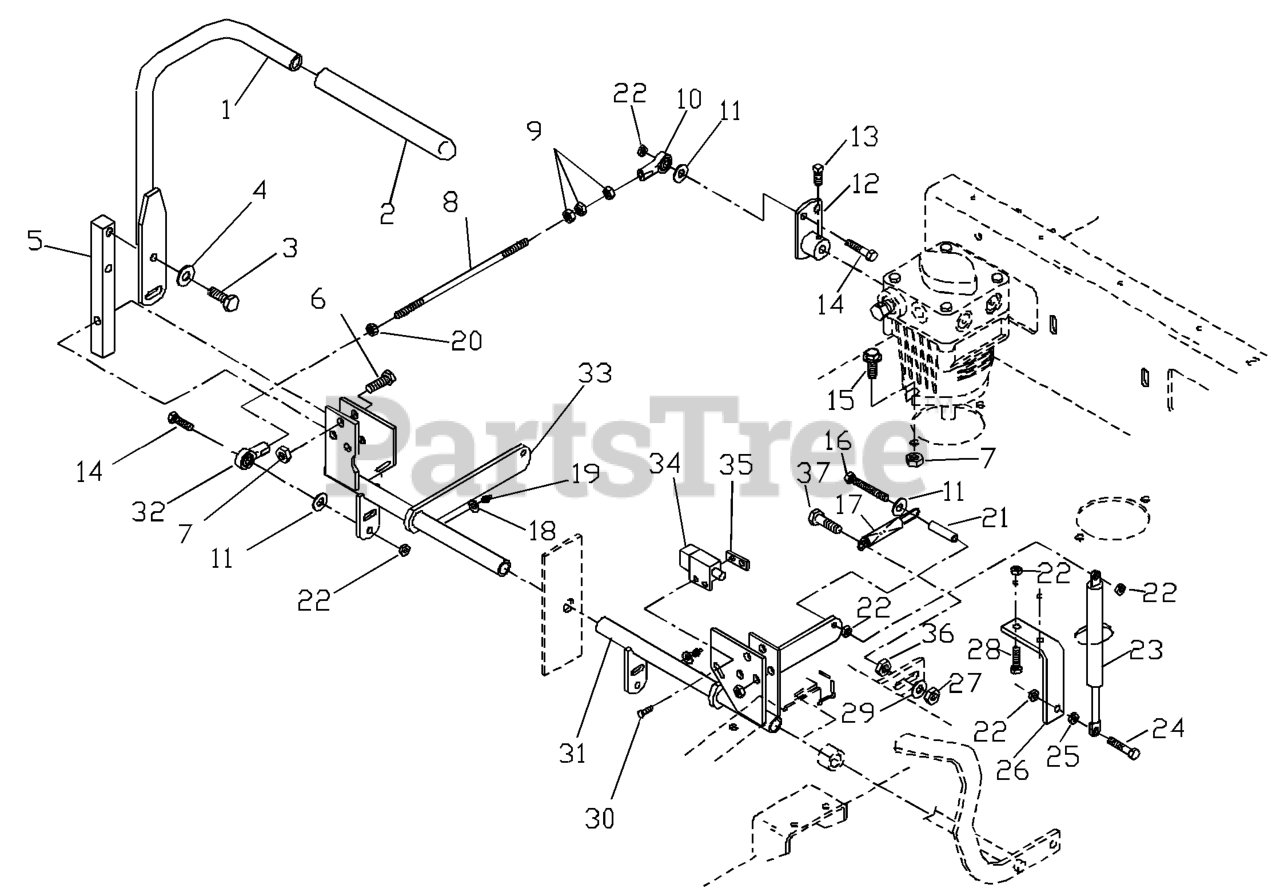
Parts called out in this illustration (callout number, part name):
1	CONTROL LEVER WELDMENT
3	HCS 3/8-16X1.GRD.5.ZD
4	WASHER, 3/8 DISC SPRING SPEC
5	CONTROL ARM
6	HCS 3/8C X 1 1/2
7	NUT 3/8C CENTERBLOCK
8	PUMP CONTROL LINK
10	BALL JOINT, RIGHT HANDED
11	WASHER 5/16 FLAT
12	PUMP LEVER
13	5/16C X 5/8 "V" POINT
14	HCS 5/16C X 1
15	4CS 3/8C X 1 SERRATED HEAD
16	TAP BOLT 5/16C X 2 1/4
19	ZERK
20	NUT 5/16F LEFTHAND
22	NUT 5/16C CENTERLOCK
24	HCS 5/16C X 1 1/4
25	NUT 5/16C WHIZ
26	BRACKET "I"
27	NUT 3/8-16 NYLOC
28	HCS 5/16C X 3/4
29	WASHER 3/8 FLAT
30	SCREW #10-24 X 5/8
31	CONTROL WELDMENT LT
32	BALL JOINT, LEFT HANDED
33	CONTROL WELDMENT RT.
34	SWITCH, INTERLOCK
35	TAPPED PLATE
36	NUT 3/8C WHIZ
37	HCS 3/8C X 2
